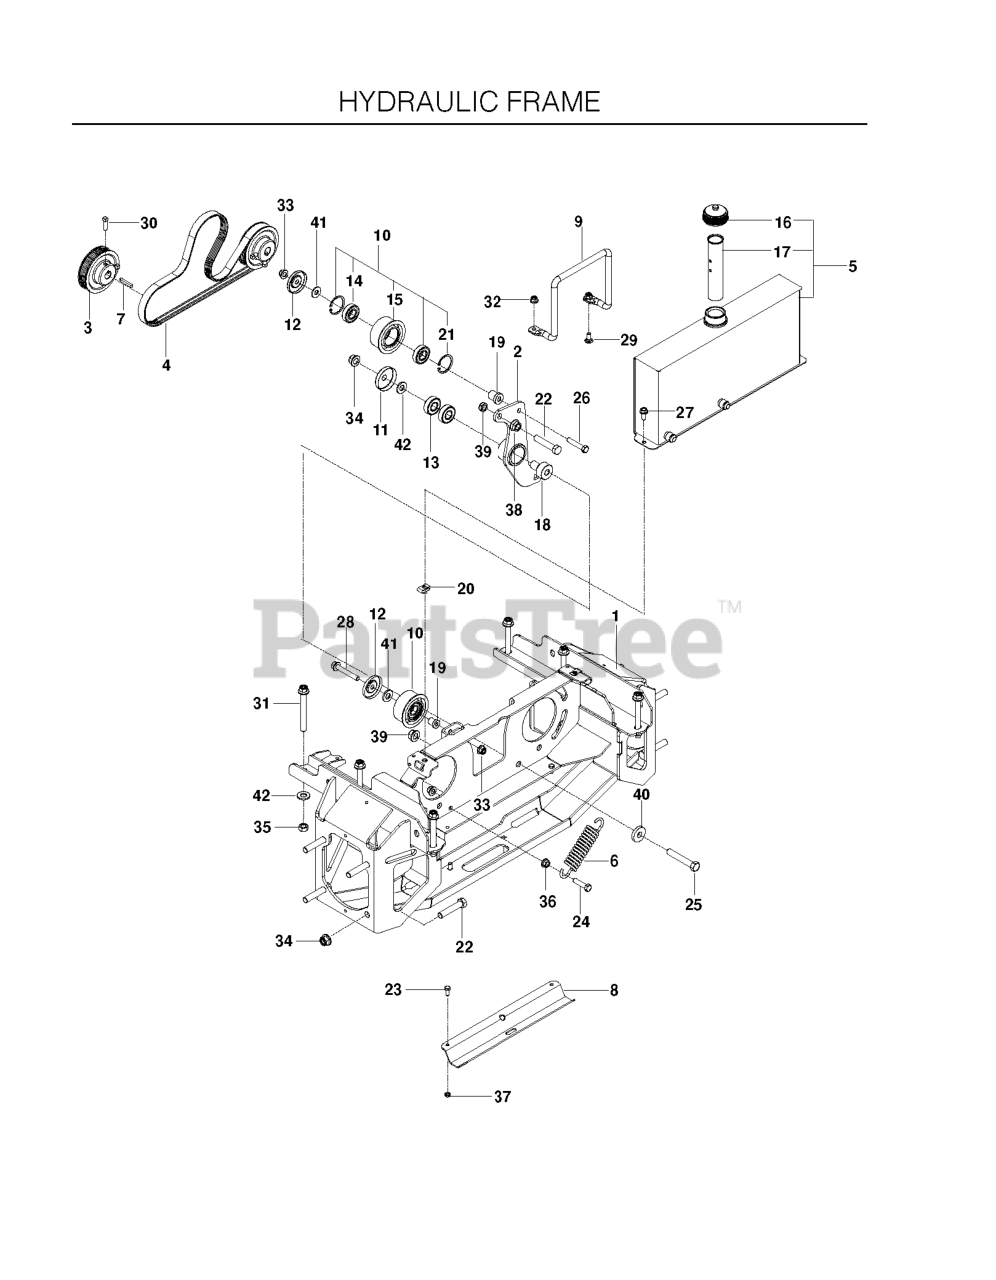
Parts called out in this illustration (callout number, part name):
1	WELDMENT, PUMP BAY, BLK
2	ASSEMBLY.IDLER.W/BEARINGS
3	PUMP SHEAVE
4	BELT, PUMP
5	ASSEMBLY, RESERVOIR
7	KEY, METRIC
8	GUARD, HOSE
9	GUIDE, BELT
10	IDLER, W/BEARINGS
11	SHIELD, DUST
12	DUST SHIELD
13	BEARING, BALL
15	IDLER, PUMP
16	CAP, HYDRAULIC
17	TUBE, ANTI-SPLASH
18	PIVOT, BEARING
19	SPACER, IDLER
20	U-CLIP 5/16-18 NUT RETAINER
21	RING, RETAINING, 1-5/8"
22	HEX SCREW 1/2-13 X 2.5" GR 5
23	HCS 1/4C X 5/8
24	HCS 3/8-16 X 1-1/2
25	SCREW, 1/2C X 3 HEX CAP
26	HCS 3/8C X 2
27	HHFS 5/16-18 X 3/4
28	HHFS 3/8-16 X 2 3/4
29	BOLT 5/16C X 3/4" CARRIAGE
30	SCREW 5/16C X 1 SQ HEAD SET
31	BOLT 7/16 X 4 GR 8 BLK PHOS
32	5/16-18 NYLOC FLANGE NUT
33	NUT 3/8-16 HEX FLG NYLOC ZD
34	NUT, 1/2-13 HEX FLG NYLOC ZD
35	7/16-14 HEX NUT W/NYL RING ZD
36	NUT 3/8C WHIZ
37	JAM NUT 1/4C (2 2 PW01)
38	NUT 1/2-13 HEX
39	NUT, HEX 1/2-13 THIN W/NY
40	WASHER .525 X 1.375 X .25
41	WASHER 3/8 FLAT
42	WASHER 1/2" FLAT
